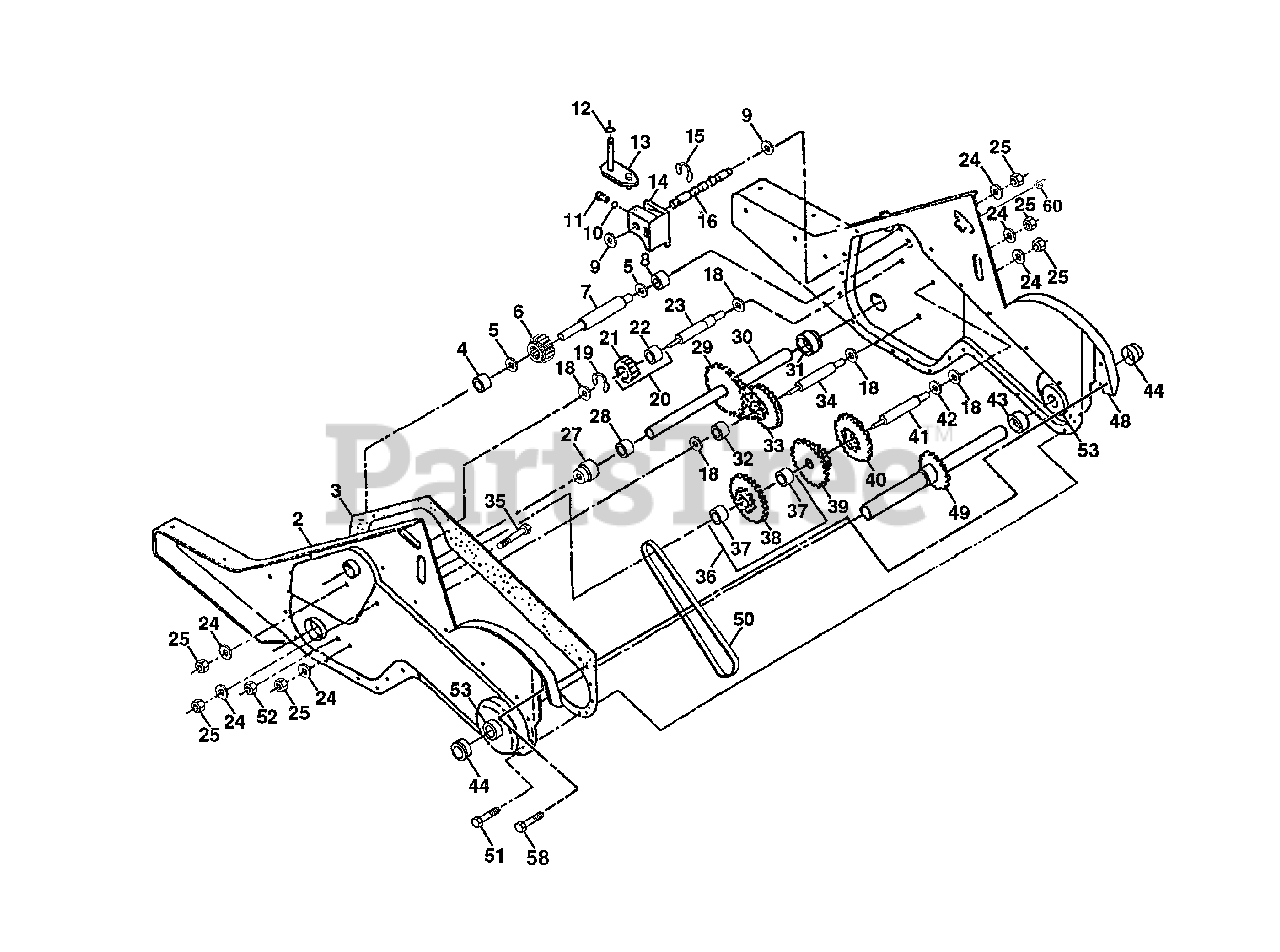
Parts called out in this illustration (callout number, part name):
1	Transmission Assembly
2	Gearcase, L.H. w/Bearing
3	Gasket, Gearcase
4	Bearing, Needle
5	Washer, Thrust 5/8 x 1.10 x 1/32
6	Pinion, Input
7	Shaft, Input
8	Bearing, Needle
9	Washer, Seal
10	Ball, Steel
11	Spring, Shift, Fork
12	O-Ring
13	Bracket, Shift
14	Fork, Shift
15	Ring, Klip
16	Shaft, Shift
18	Washer
19	Ring, Klip
20	Gear, Assembly, Reverse Idler
21	Gear, Reverse Idler
22	Bearing, Needle
23	Shaft, Reverse Idler
24	Washer, Lock 7/16
25	Nut, Hex 7/16-20
27	Bearing, Shaft, Ground Drive L.H.
28	Spacer 0.765 x 1.125 x 1.23
29	Chain #35-50 Pitch
30	Ground Shaft Assembly
31	Bearing, Shaft, Ground Drive R.H.
32	Spacer 0.70 x 1.00 x 1.150
33	Sprocket and Gear Assembly
34	Shaft, Reduction (2nd)
35	Screw, Whiz, Lock 5/16-18 x 3-1/2
36	Sprocket Assembly w/Bearing
37	Bearing, Needle
38	Sprocket, Tine
39	Gear, Cluster, Red 1st & 2nd
40	Gear, Reverse
41	Shaft, Reduction (1st)
42	Washer, Thrust
43	Spacer 1.01 x 1.75 x 0.760
44	Seal, Asm. Oil
48	Gearcase, R.H. w/Bearing
49	Shaft, Tine
50	Chain, Roller #50-50 Pitch
51	Screw 1/4-20 x 1/2
52	Nut, Hex 5/16-18
53	Kit, Bearing, Tine Shaft
54	Screw 1/4-20 x 3/4
60	Fitting Grease
60	Grease, Plastilube #1
